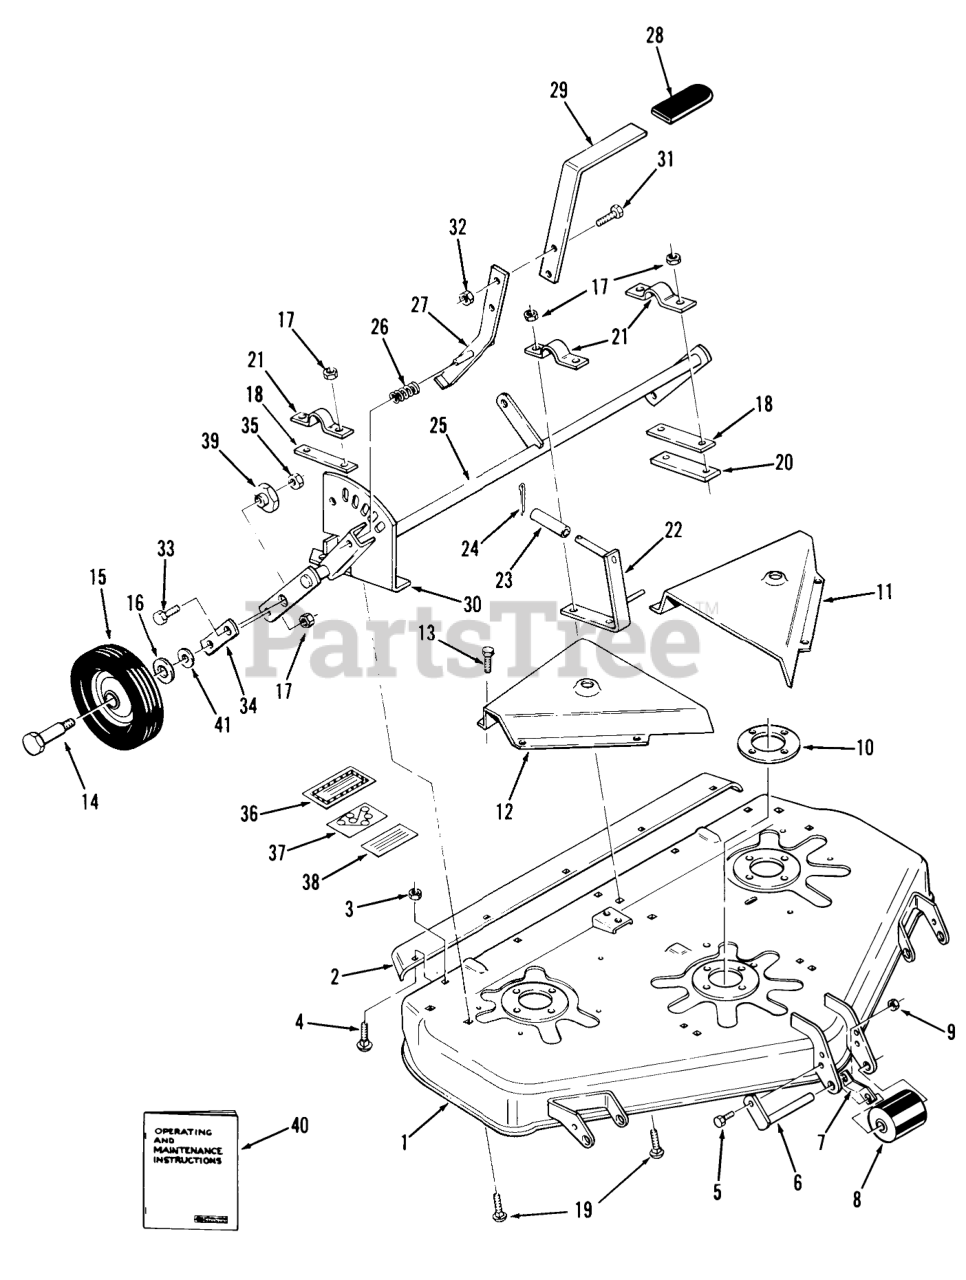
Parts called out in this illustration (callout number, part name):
1	Mower Deck
2	Rear Chute Extension
3	Nut
4	CARRIAGE BOLT -4
5	H H C S
6	Roller Shaft
7	SPRING ROLLER STOP
8	Roller
9	Nut
10	PLATE-SPINDLE
11	Belt Cover LH
12	Belt Cover RH
13	Bolt
14	BOLT-SHOULDER
15	Wheel 6 x 1.75
16	WASHER
17	Nut
18	Strap 1/16
19	Bolt
20	Strap
21	CLAMP
22	Bracket Guide
23	SPACER
25	ASSY-GAGE WHL SUPT
26	SPRING-COMPRESSION
27	Lever
29	HANDLE-EXTENSION R
30	Quadrant
31	Bolt
32	Nut
33	Bolt
34	Wheel Plate
35	Nut
36	Caution Decal
37	DECAL-HEIGHT BELT
38	Decal-Caution
39	STEERING ARM
40	Operating and Maintenance Instructions
41	Washer
